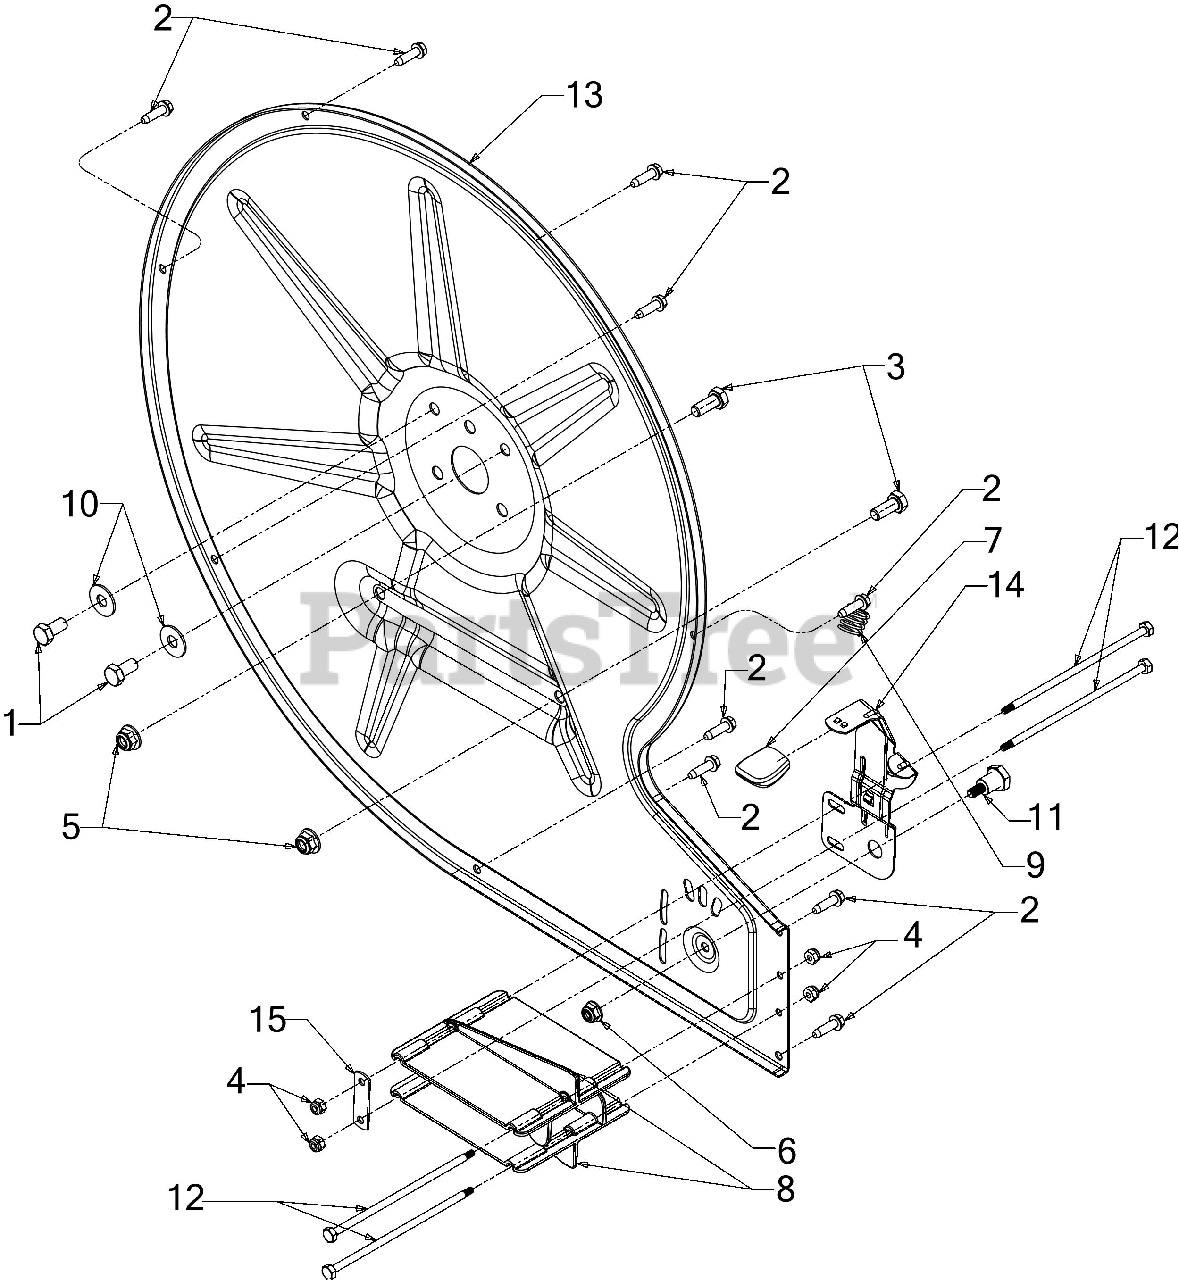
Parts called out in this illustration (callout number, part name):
1	HEX SCREW 5/16-24 x .62
2	SCREW #12-16 .75
3	SCREW 5/16-18 x .75 GR5
5	FLANGE LOCK NUT 5/16-18
6	FLANGE LOCK NUT
7	HEIGHT ADJUSTMENT KNOB
8	LOUVER BLOWER PLATE
9	COMPRESSION SPRING
10	BELL WASHER .337 X.867 x .057
11	SHOULDER SCREW .437X.50 1/4-20
12	SHOULDER SCREW 18 x 4.8 8-32 GR5
15	GUIDE LOUVER PLATE
